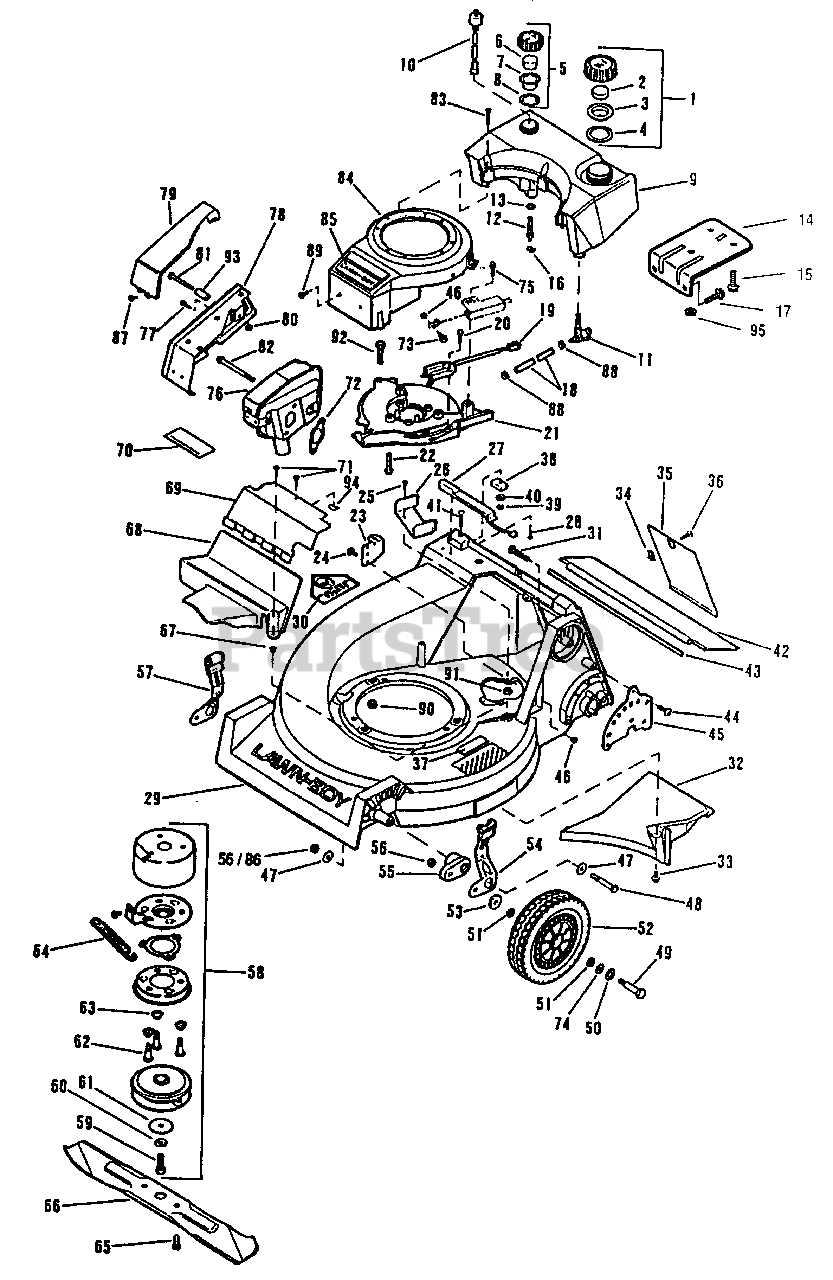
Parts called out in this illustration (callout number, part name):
1	Fuel Cap Assembly
2	Baffle
3	Cover
4	Gasket
5	Oil Cap Assembly
6	Filter
7	Cover
8	Gasket
9	Fuel/Oil Tank (BMRB)
9	Fuel/Oil Tank (BMRC & D)
10	Switch-Low Oil (BMRB)
11	Fuel Shut-Off Valve
12	Oil Fining Assy
13	O-Ring
14	Fuel Tank Bracket
15	Screw
16	Clamp-Oil Hose
17	Screw-Fuel Tank Bracket to Block
18	Fuel Line
19	Brake Interlock Switch
20	Screw-Interlock Switch to Plate
21	Engine Mounting Plate
22	Screw-Mounting Plate to Engine
23	Cable Anchor
24	Screw-Anchor to Housing
25	Screw-Belt Guide to Housing
26	Belt Guide
27	Switch Assy-Bag Lock (BMRB)
28	Screw
29	Housing Assy (BMRB & D)
29	Housing Assy (BMRC)
30	Decal-Blade Contact Warning
31	Handle Mounting Bolt
32	Baffle
33	Screw
34	Speednut
35	Access Door
36	Screw
37	Decal-Foot Pad
38	Magnet Assembly
39	Nut
40	Lockwasher
41	Screw (BMRB & D)
42	Trailing Shield
43	Rod-Trailing Shield
44	Screw
45	Height Adjust Plate
46	Nut
47	Washer
48	Screw
49	Bolt-Wheel
50	Washer-Wheel Bolt
51	Felt Washer
52	Wheel and Tire Assembly-Front
53	Washer
54	Knob and Spring Assembly-L.H.
55	Front Height Adj Arm (BMRB & D)
56	Nut (BMRB)
57	Knob and Spring Assembly-R.H.
58	Clutch and Brake Assembly
59	Screw
60	Lockwasher
61	Washer
62	Screw
63	Spring-Compression
64	Spring-Extension
65	Screw-Blade
66	21" Blade
67	Grommet
68	Lower Drive Cover
69	Upper Drive Cover w/Decal
70	Decal-Warning
71	Screw (BMRB)
72	Exhaust Gasket
73	Bolt
74	Washer-Shim
75	Screw
76	Muffler
77	Screw-Muffler Guard
78	Muffler Guard Assembly
79	Muffler Cover
80	Pushnut
81	Screw-Muffler Guard
82	Screw-Muffler
83	Screw-Fuel Tank
84	Shroud and Applique Assembly
85	Applique
86	Nut (BMRC & D)
87	Screw-Muffler Guard
88	Clamp-Fuel Line
89	Screw-Shroud
90	Locknut-Mting Plate to Housing
91	Locknut-Belt Guide to Housing
92	Screw-Mting Plate to Housing
93	Spacer-Muffler Guard
94	Speednut
95	Nut-Hex Flange
